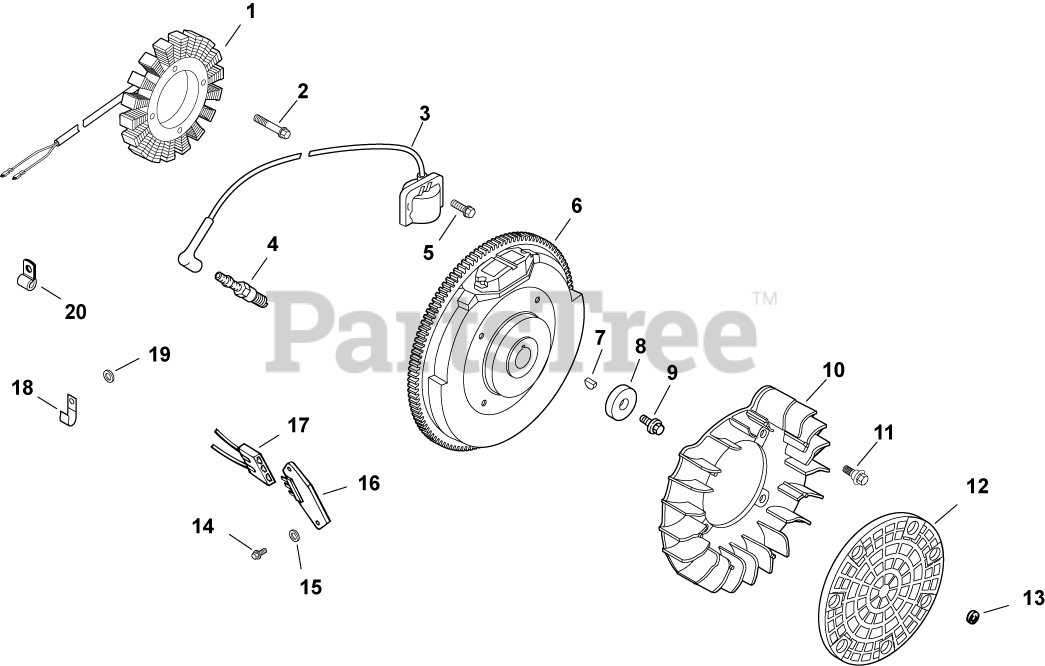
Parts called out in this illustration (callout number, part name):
1	KIT, 15 / 20 AMP STATOR
2	SCREW, M5X0.8X25 - (#25086402S)
3	KIT, MODULE IGNTN (CDI FIXED)
4	PLUG, SPARK (STD)
5	SCREW, FLG THD FRM M5X.8X20-(#25086399S)
6	FLYWHEEL, PAINTED-USE 24 025 55-S
7	KEY, 3/16" X 5/8"
8	WASHER, FLAT 13/32"
9	SCREW, FLG M10X1.5X45 - (#25086361S)
10	FAN - USE (#24 157 11-S)
11	BOLT, SHOULDER
13	SCREEN, GRASS
14	SCREW, PHL HD #11-16X7/8"
15	WASHER, FLAT 3/16"
16	REG/RECT-15 AMP (KM)-USE 41 403 10-S
17	CONNECTOR, BODY (KM)-USE 25 155 41-S
18	CLIP, CABLE
19	WASHER, FLAT 1/4" (O.D. 1/2")
20	CLIP, TUBE & WIRING (KM)
